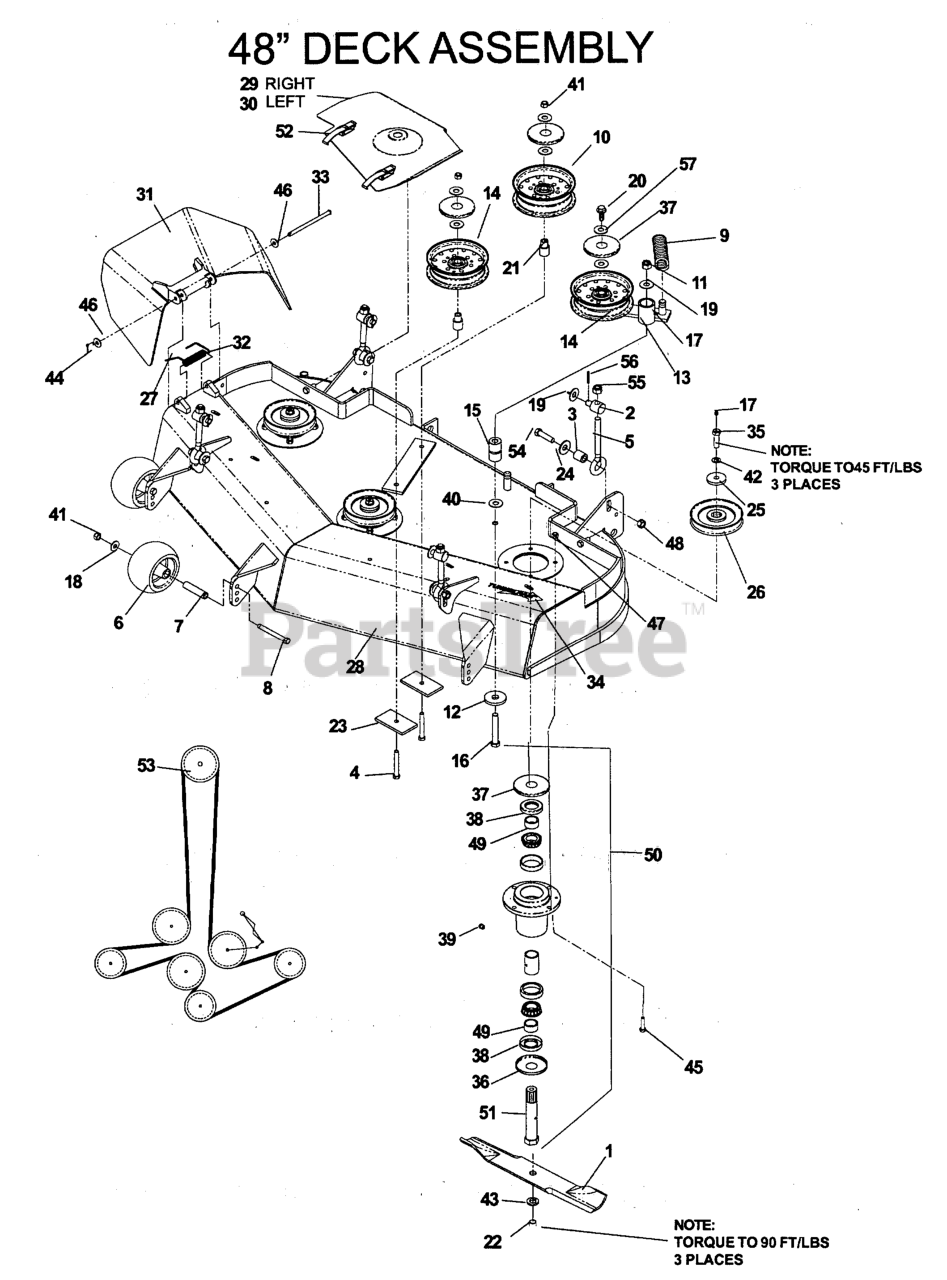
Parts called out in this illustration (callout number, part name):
1	BLADE OEM 16 1/4"
4	SCREW 3/8C X 2 3/4 HEX CAP
6	ANTI-SCALP ROLLER
8	HCS 3/8C X 3 1/2
10	IDLER PULLEY (TALL)
11	NUT 1/2-13 HEX NYLOC ZD
12	WASHER, SUPPORT
14	IDLER PULLEY
15	PIVOT BUSHING
16	HCS 1/2C X 3 1/4
17	ZERK
18	WASHER 3/8 FLAT
19	WASHER 1/2 FLAT
20	4CS 3/8C X 1 SERRATED HEAD
21	IDLER BUSHING
22	HCS 5/8F X 1 1/4
23	SUPPORT PLATE
24	SPRING WASHER - .50
25	SPINDLE WASHER
26	RP PULLEY - 42/48"
27	CAP-SLEEVE
28	DECK W/DECALS 48" HUS
29	48 BELT SHIELD ASM - RH
30	48 BELT SHIELD ASM - LH
31	DISCHARGE CHUTE 48"
32	SPRING - TORSION
33	PIN-CLEVIS 5/16 DIA X 5.19 ZD
34	DECAL, TUNNEL RAM 6"
35	HCS 7/16-20 GD 8 SPEC
36	BOTTOM DUST CAP
37	TOP DUST CAP
38	SHAFT SEAL
39	PLUG-VENTED
40	WASHER 1/2 X 1.44 HRD ZD
41	NUT 3/8-16 NYLOC
42	WASHER 7/16 LOCK
43	LOCKWASHER 5/8
44	RP_COTTER PIN 1/8 X 3/4
45	HCS 5/16C X 1 1/4
46	WASHER 5/16 FLAT
47	NUT 5/16 NYLOC
48	NUT 7/16C CENTERLOCK
50	SPINDLE ASSY - 52/61"
51	MINI SPINDLE
52	DRAW LATCH
53	BELT, DECK 48"
54	HCS 7/16 - 14 X 1 3/4
55	NUT 1/2-13 HEX NYLOC ZD
56	PIN COTTER 1/8 X 1 ZD
